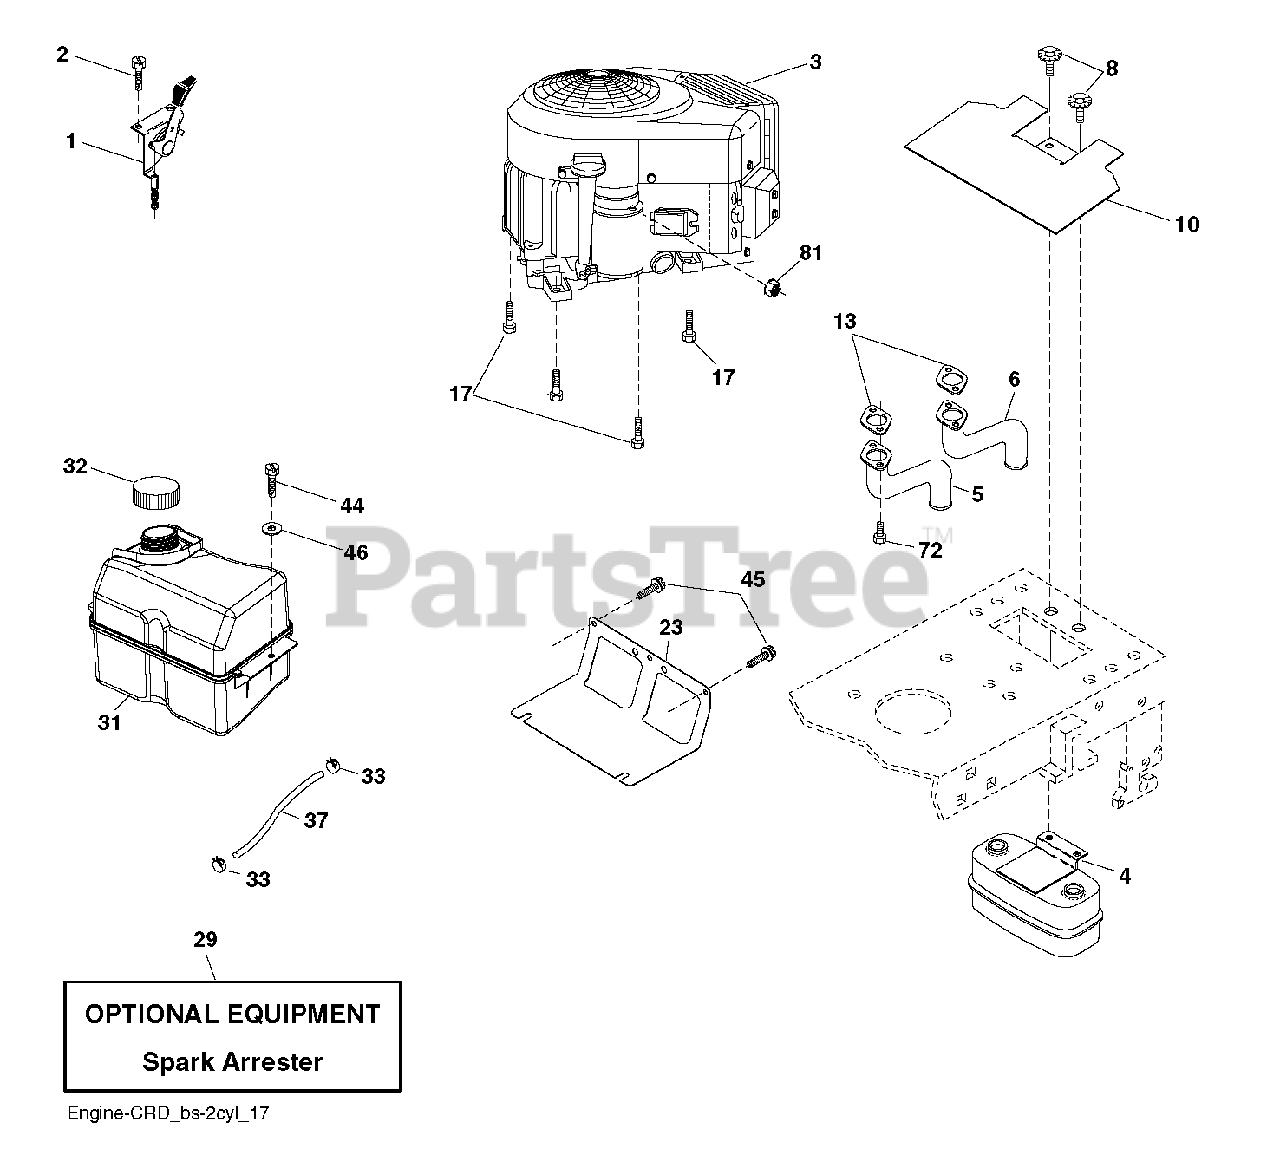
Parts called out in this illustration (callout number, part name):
1	CONTROL.TH/CK.COBRA.B&S.TWN.
2	SCREW.#10 X 0.750.BOS
4	MUFFLER.TWIN.CYL.LOW.TONE
5	RP.EXHAUST.TUBE.LH.BS/TWIN
6	EXHAUST.TUBE.RH.BS/TWIN
8	BOLT, 5/16-18 X 1 3/4
10	SHIELD.HEAT.MUFFLER
13	GASKET.MUFFLER
17	SCREW.3/8-16
23	SHIELD.BROWNING.PNT.GT.V2
29	KIT.SPARK ARRESTOR 794945 B&S
31	TANK.ASM.FUEL.FR.2.5GA.
32	CAP ASM.FUEL.2.25"FR.
33	HOSE CLAMP
37	LINE.FUEL.20
44	SCREW HEXWSHR 1/4-20X3/4
45	SCREW, 3/8-16X3/4
72	SCREW.SOCKET.HEAD.5/16-18
81	NUT
